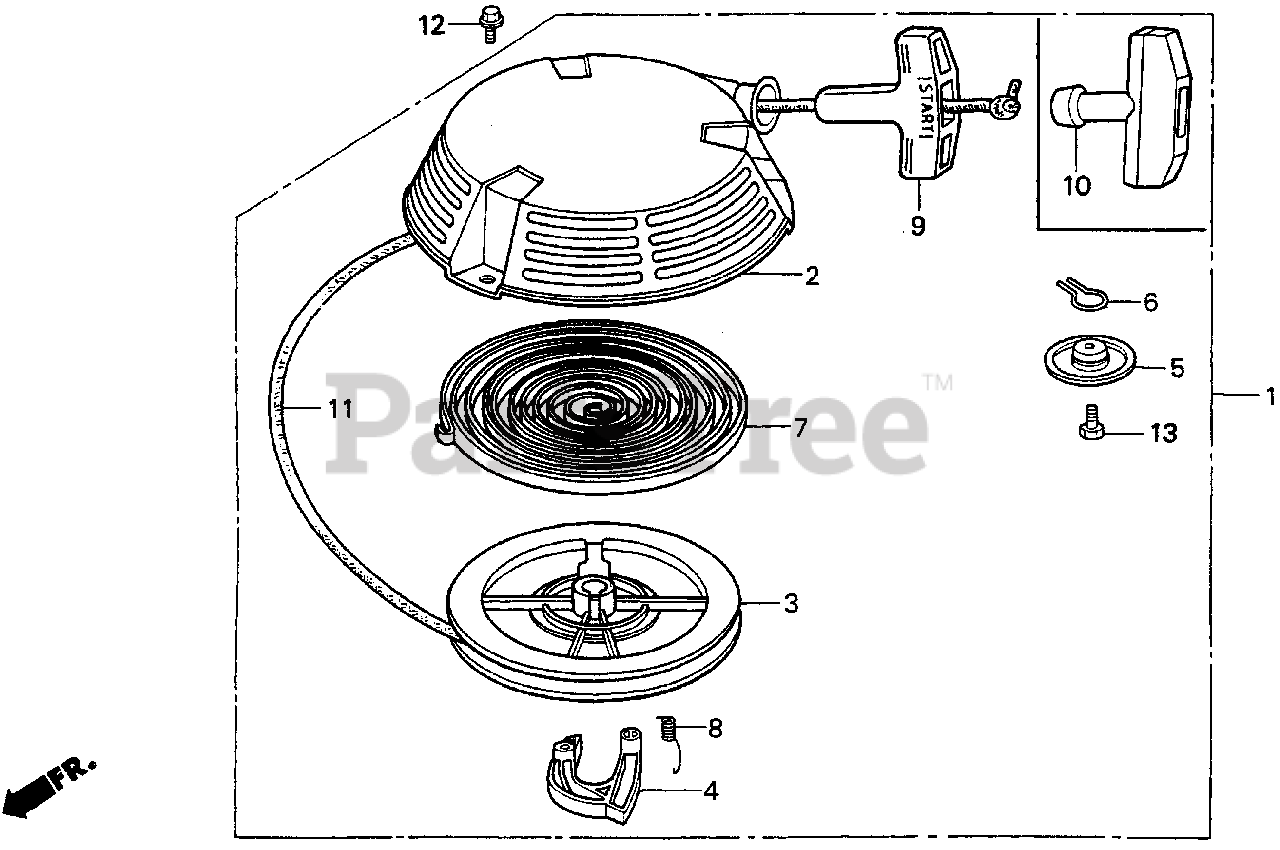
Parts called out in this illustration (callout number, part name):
1	STARTER ASSY., RECOIL *R280* (POWER RED)
2	CASE, RECOIL STARTER *R280* (POWER RED)
3	PULLEY, RECOIL STARTER
4	RATCHET, STARTER
5	PLATE, FRICTION
6	SPRING, FRICTION
7	SPRING, RETURN
8	SPRING, RETURN
9	KNOB, RECOIL STARTER
10	KNOB, STARTER
11	ROPE, RECOIL STARTER (#4X55")
11	ROPE, LONG (55")
12	BOLT, FLANGE (6X8)
13	BOLT, HEX. (6X20)
